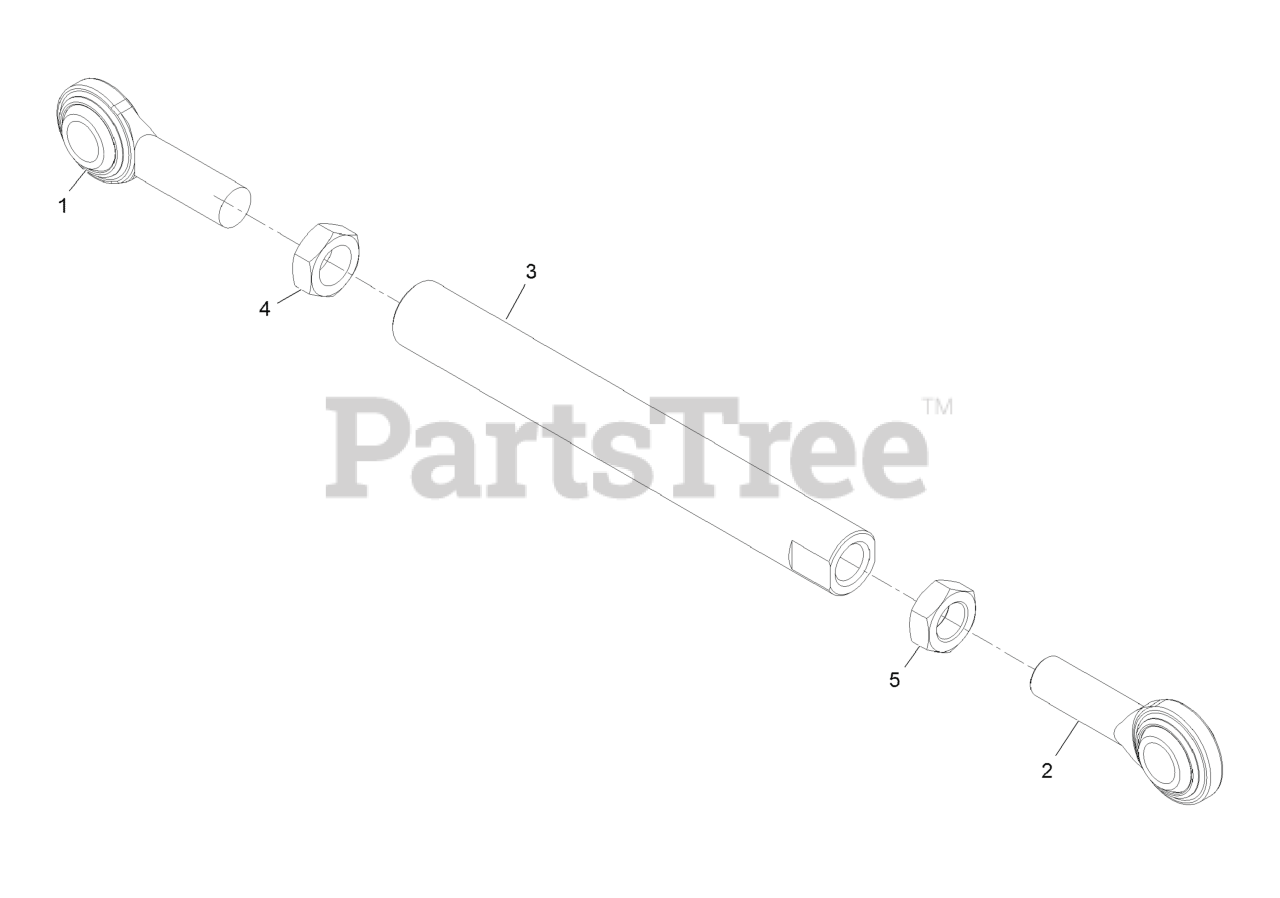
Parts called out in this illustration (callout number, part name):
1	BALLJOINT-SPHERICAL
2	BALLJOINT-SPHERICAL
3	ROD, LIFT
4	NUT-JAM
5	NUT-JAM
